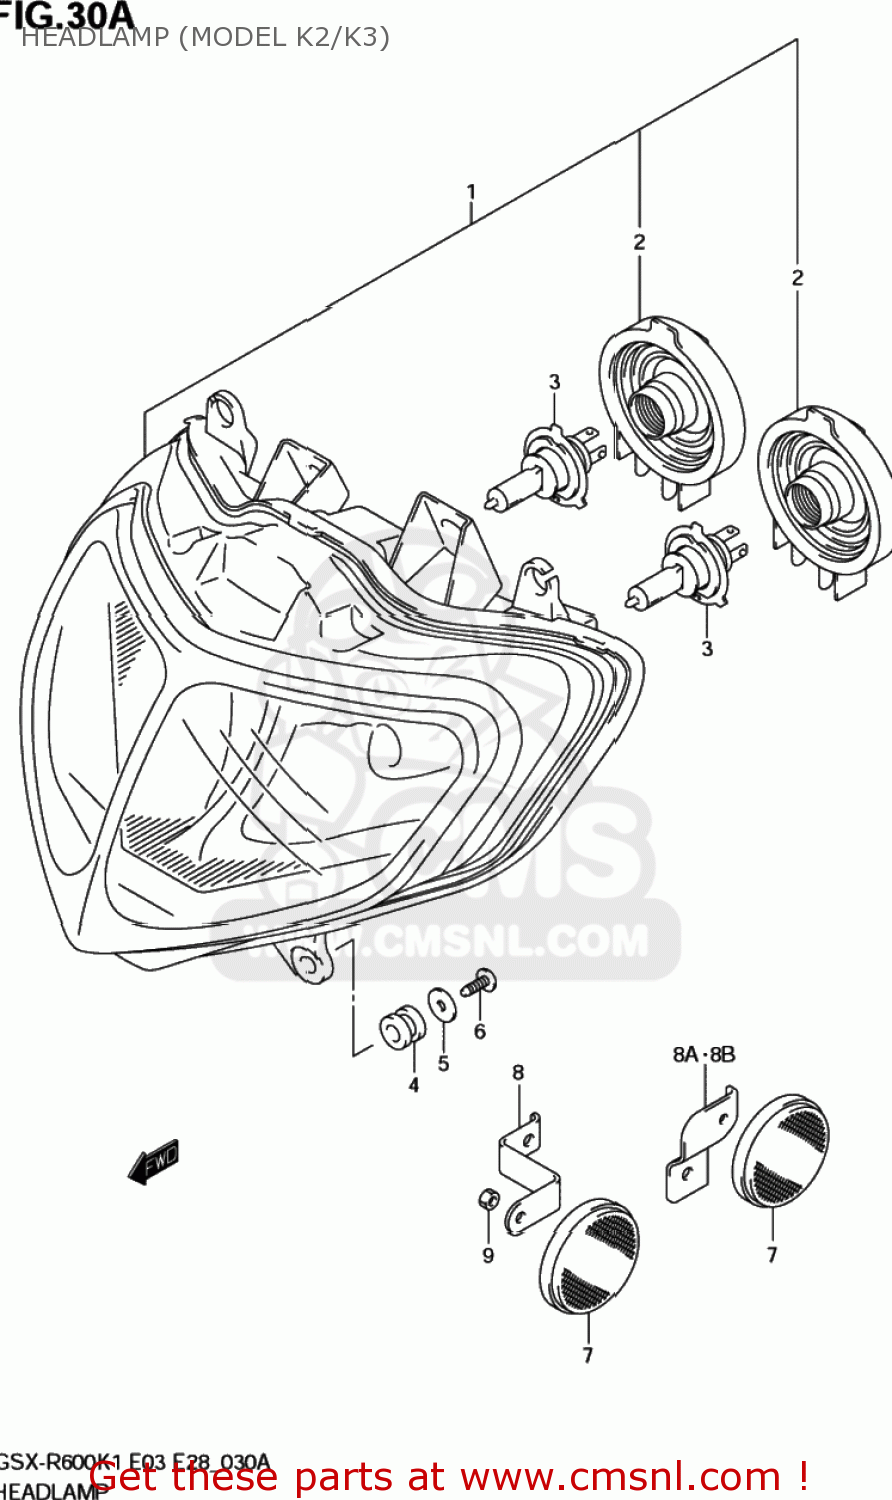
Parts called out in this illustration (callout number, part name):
1	HEADLAMP ASSY
2	COVER,SOCKET
3	BULB(12V60/55W,H4)
4	CUSHION
5	WASHER(5.5X18X1)
6	SCREW
7	REFLECTOR,REFLEX
8	BRACKET,FR SIDE RR
8A	BRACKET,FR SIDE,R
8B	BRACKET,FR SIDE,L
9	NUT
